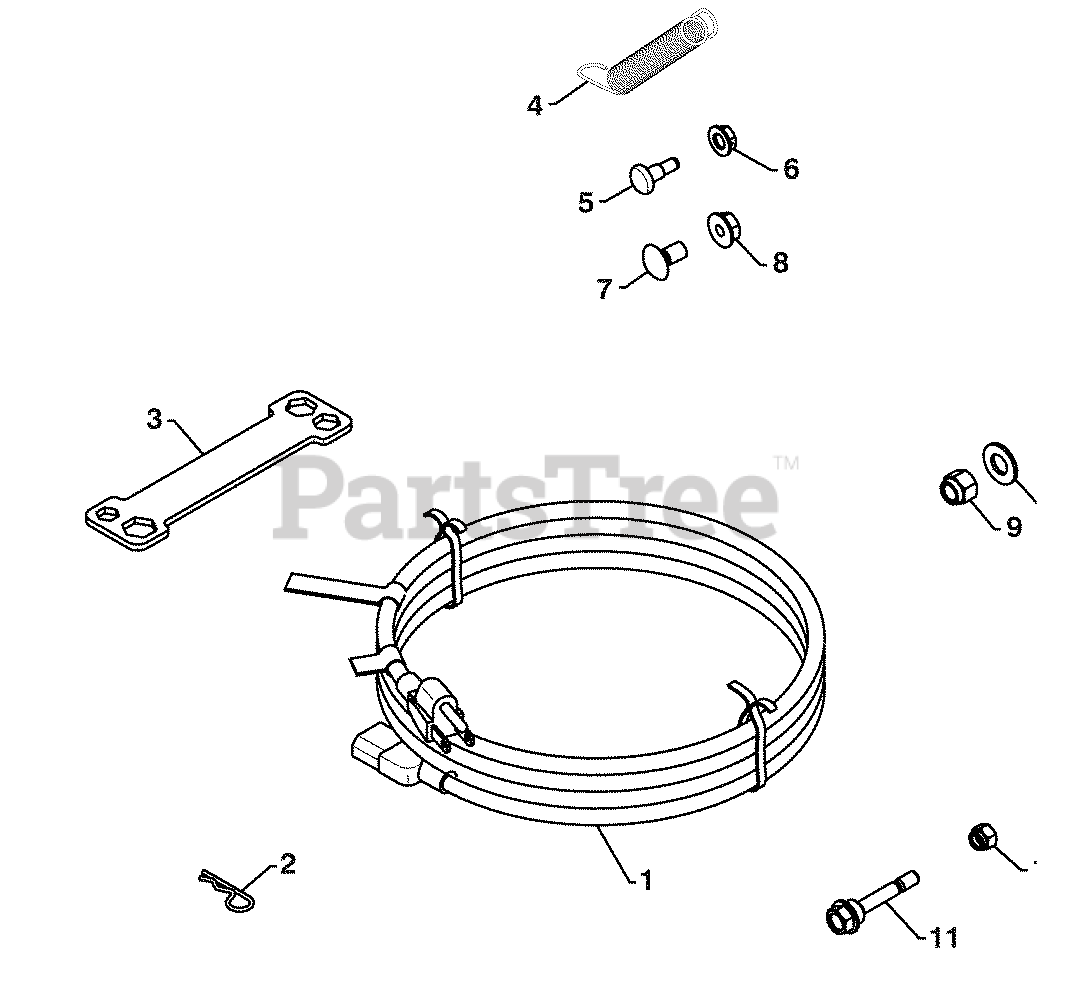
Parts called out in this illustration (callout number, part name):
1	POWER CORD
2	RETAINER PIN
4	REMOTE SPRING
5	SHOULDER BOLT 1/4-20
6	LOCKNUT 1/4-20
7	CARRIAGE BOLT 5/16-18 X 5/8
8	LOCKNUT 5/16-18
9	LOCKNUT 3/8-16
10	WASHER 3/8
11	SHEAR BOLT 1/4-20 X 1-13/16
12	LOCKNUT 1/4-20
